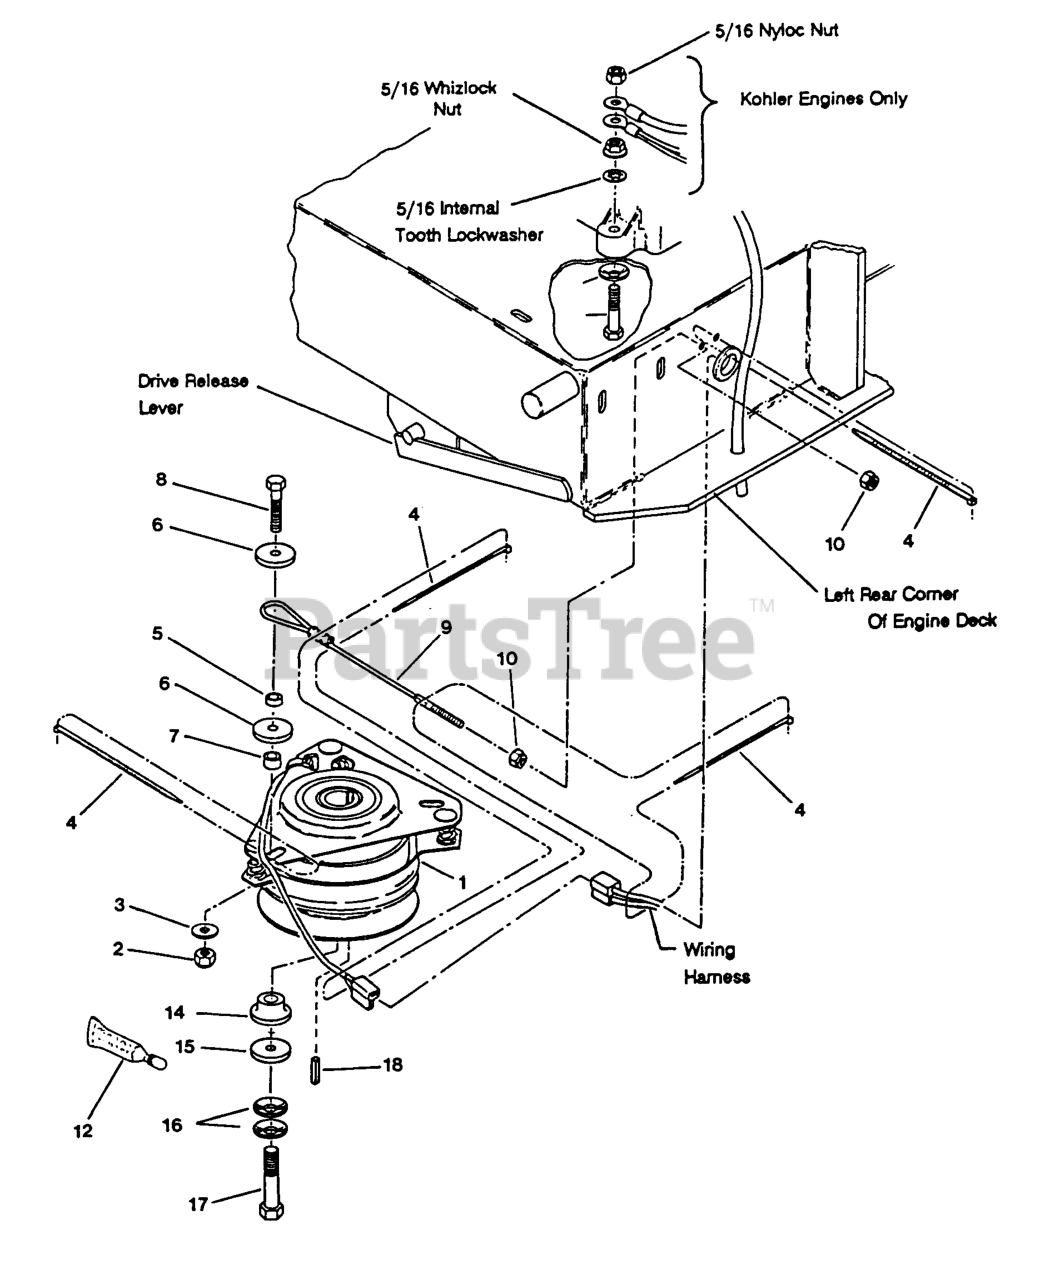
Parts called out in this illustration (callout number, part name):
4	TIE-CABLE
7	SPACER,CLUTCH ANCHOR
12	PRO-LOCK,NUT TYPE
13	WASHER-SPRING
14	BUSHING,CLUTCH KEEPER
16	WASHER-SPRING
